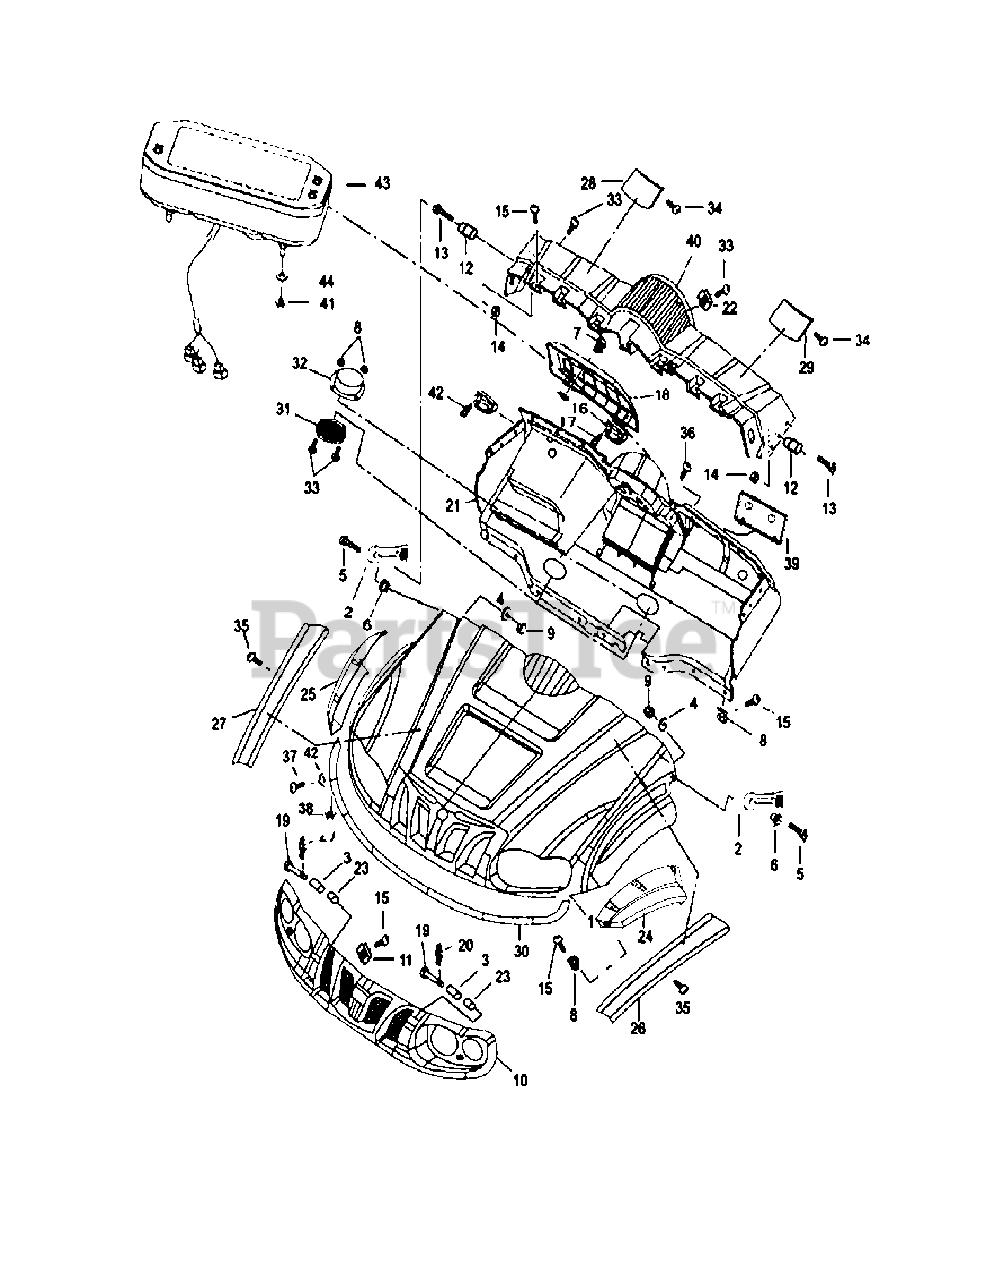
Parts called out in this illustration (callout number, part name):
1	HOOD - YELLOW
1	HOOD - CAMO
2	Front Cover Latch I
3	Bushing 25×13×30
4	Washer6×18×1.6
5	Hexagon Flange Bolt M6×30
6	Bushing 6.5×9×22×17
7	Glove Compartment Locker
8	Hexagon Flange Nut M6
9	Cap Nut M6×12
10	Headlight Cover
11	Screw Thread Clip M6×2
12	Latch Fixed Seat
13	Hexagon Flange Bolt M6×35
14	Hexagon Flange Self-Lock Nuts M6
15	Cross large plate head screw M6×16
16	Plastic Jaw
17	Cross Plate Head Tapping ScrewST3.9×13
18	Glove Compartment Cover
19	Shaft 12.5×89
20	Cotter pin 2×32
21	Dash Board
22	Screw Thread Clip M6×5
23	Bushing25×13×13
24	Left Fender, Front Cover
25	Right Fender, Front Cover
26	Left Strip, Front Cover
27	Right Strip, Front Cover
28	Decoration Cover
29	Left Strip, Connecting Cover
30	Front Binding Strip, Front Cover
31	Speaker Cover
32	Speaker Box
33	Cross Large Plate Head Screw M6×20
34	Cross Plate Head Tapping ScrewST3.9×13
35	Cross Small Plate Head Tapping Screw ST4.2×13
36	Cross Countersunk Head Tapping Screw St6×20
38	Hexagon flange nut M5
39	Cd Player Cover
40	CONNECTING COVER- YELLOW
40	CONNECTING COVER- CAMO
41	Hexagon Flange Nut M6
42	Cushion 5×15×1.2
43	Meter Assy(EFI Engine)
44	Washer6×18×1.6
